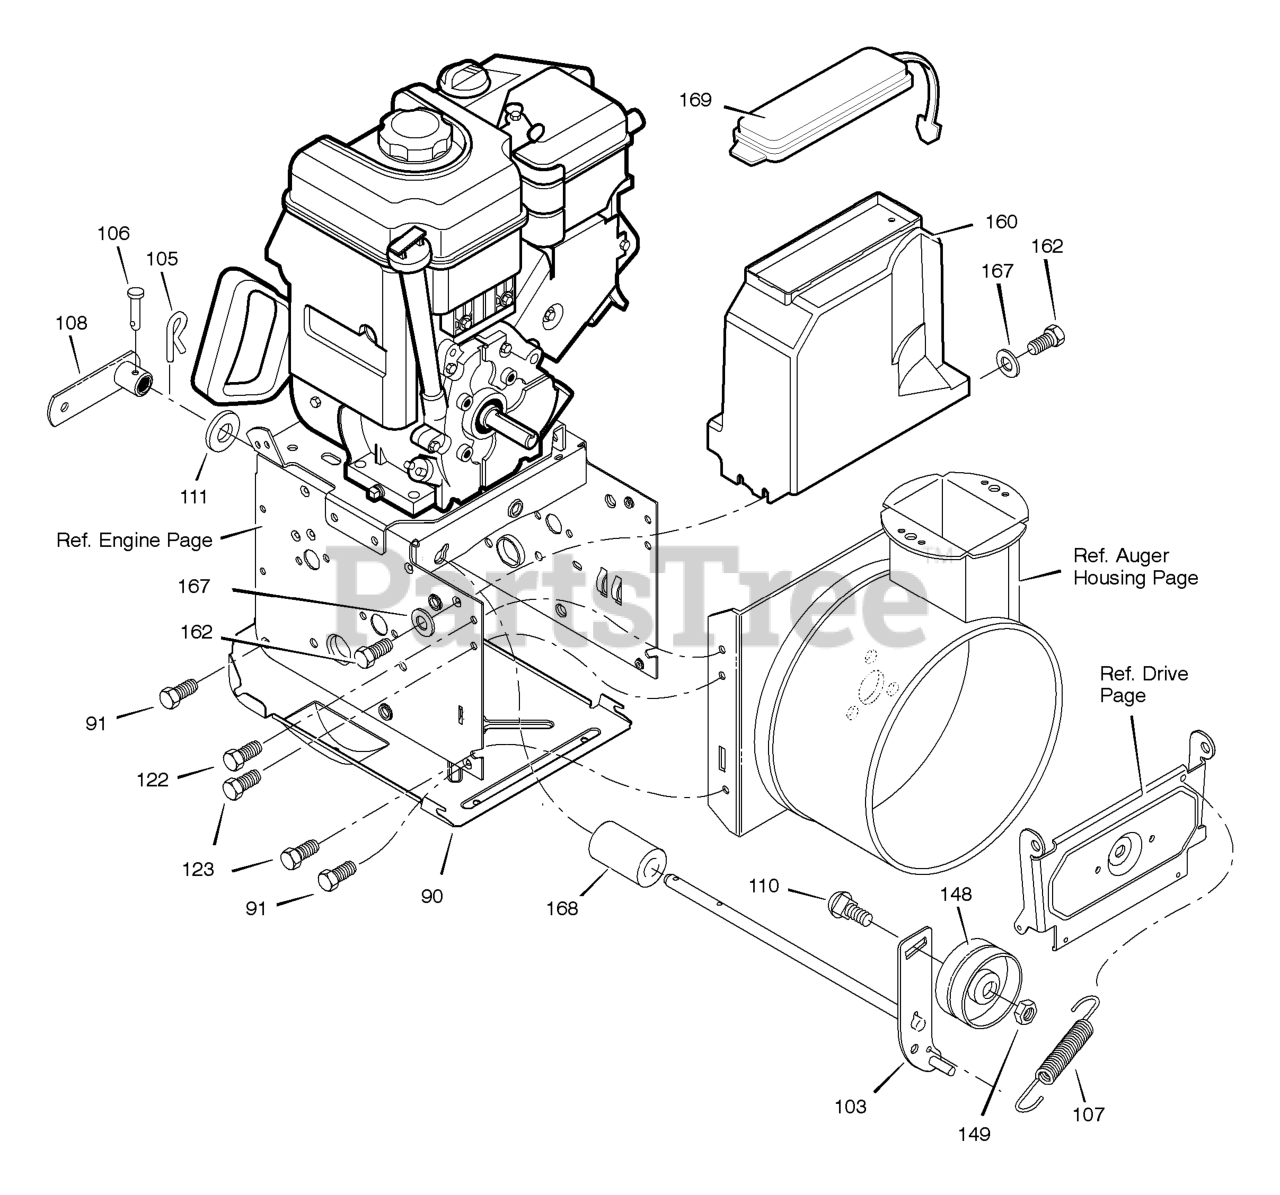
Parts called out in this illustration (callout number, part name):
90	COVER, BOTTOM
91	SCREW, 1/4-20X .63
103	IDLER ASSEMBLY, AUGER
105	PIN, HAIR .38DIAX1.64LG
106	PIN, CLEVIS 3/16" DIA
107	SPRING, TENSION
108	ASSY., SPRING ATTACH
110	BOLT, 3/8-16X1.25 CARR.
111	WASHER, FLAT
122	SCREW, TAP 5/16-18 X .50
123	SCREW, TAP 5/16-18 X .75
148	PULLEY, IDLER
149	NUT, JAM 3/8-16
160	COVER, BELT
162	SCREW, TAP
167	WASHER, FLAT
168	SPACER, AUGER BRACKET
169	LID, TOOL BOX
